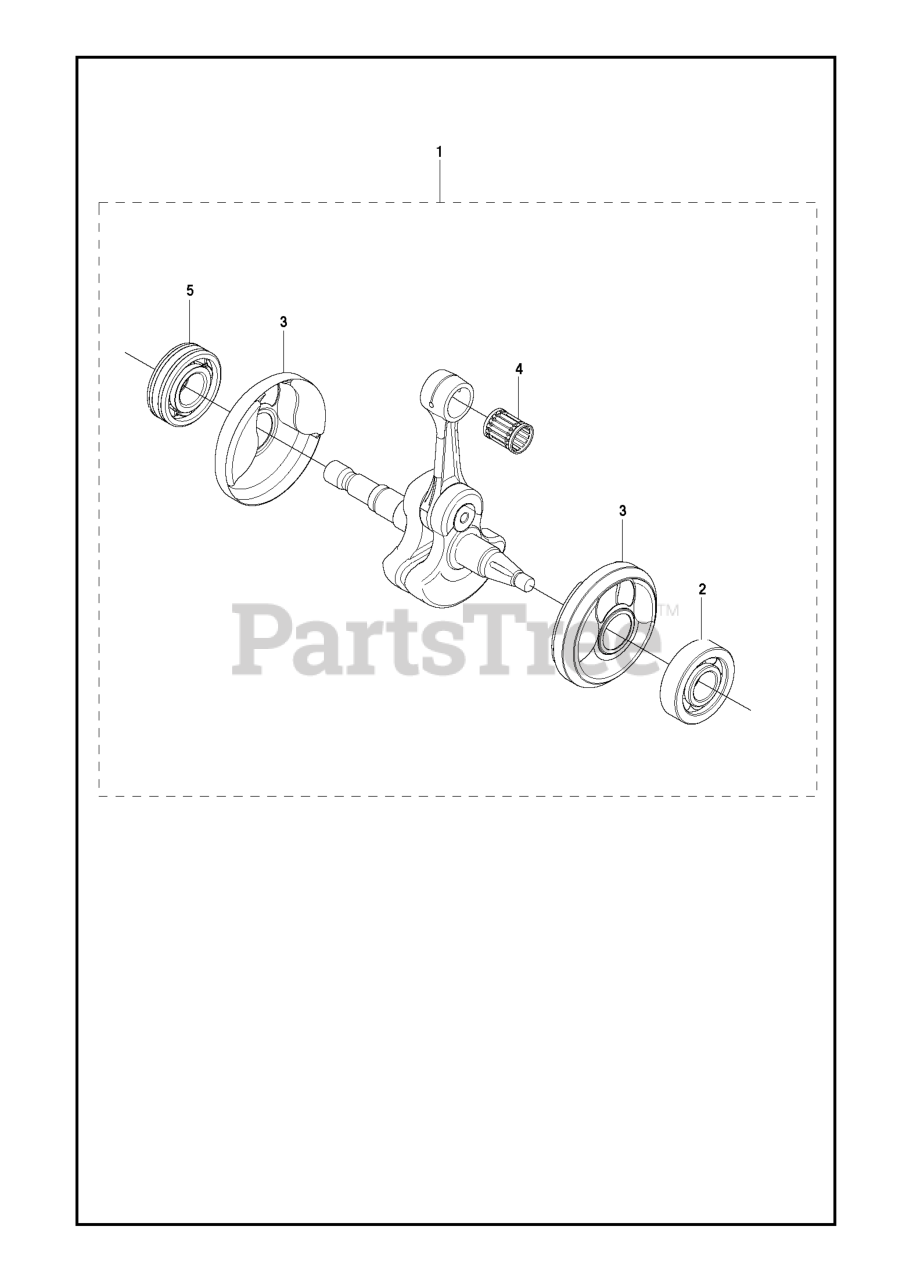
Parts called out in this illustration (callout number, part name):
1	CRANKSHAFT ASSY
2	BALL BEARING 6203C3QE6
4	SUPPORT BUSHING
5	BALL BEARING 6203 EC-C13/20-JR
